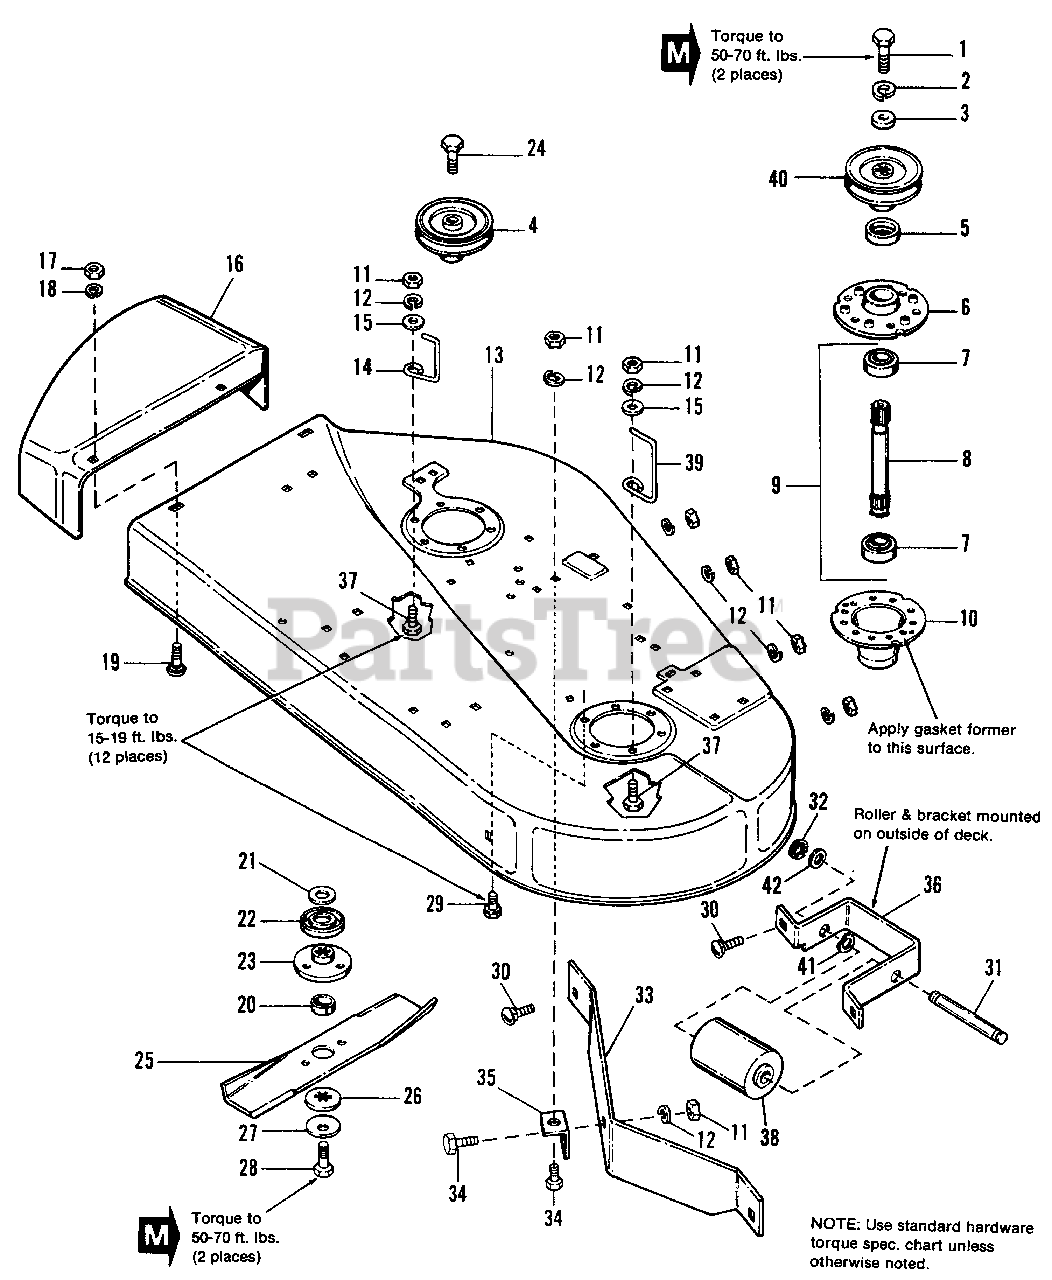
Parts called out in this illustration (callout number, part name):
1	CAPSCREW, Hex Hd., 7/16-14 x 3-1/2
2	LOCKWASHER, 7/16
3	WASHER, Special
4	PULLEY ASSY.
5	SHIELD, Bearing Upper, Arbor
6	HOUSING, Top
8	SHAFT, Arbor (Incl. Ref. No. 20)
9	SHAFT & BEARING ASSY. (Incl. Ref. Nos. 7, 8 & 20)
10	HOUSING, Bottom
11	NUT, Hex, Full, 5/16-18
12	LOCKWASHER, 5/16
13	HOUSING, 36" (Incl. Safety Decals)
15	WASHER, 5/16
16	DEFLECTOR, Mower
17	NUT, Hex, Full, 3/8-16
18	LOCKWASHER, 3/8
19	BOLT, Carriage, 3/8-16 x 3/4
20	COLLAR, Arbor
21	WASHER, Shim
22	SHIELD, Grass
23	ADAPTOR, Blade
24	CAPSCREW, Hex Hd., 7/16-14 x 2-3/4
26	WASHER, Spline
27	WASHER, Cup
28	CAPSCREW, Hex Hd., 7/16-14 x 1
29	SCREW, Hex, Wash. Hd., Taptite, 5/16-18 x 3/4
30	BOLT, Carriage, 5/16-18 x 3/4
31	SHAFT, Roller, Center
32	E-RING
33	BAFFLE
34	CAPSCREW, Hex Hd., 5/16-18 x 3/4
35	BRACKET, Mower
36	BRACKET, Center, Roller
37	SCREW, Hex Hd., Taptite, 5/16-18 x 1
40	PULLEY ASSY.
41	WASHER, Wave
42	WASHER, Nylon
